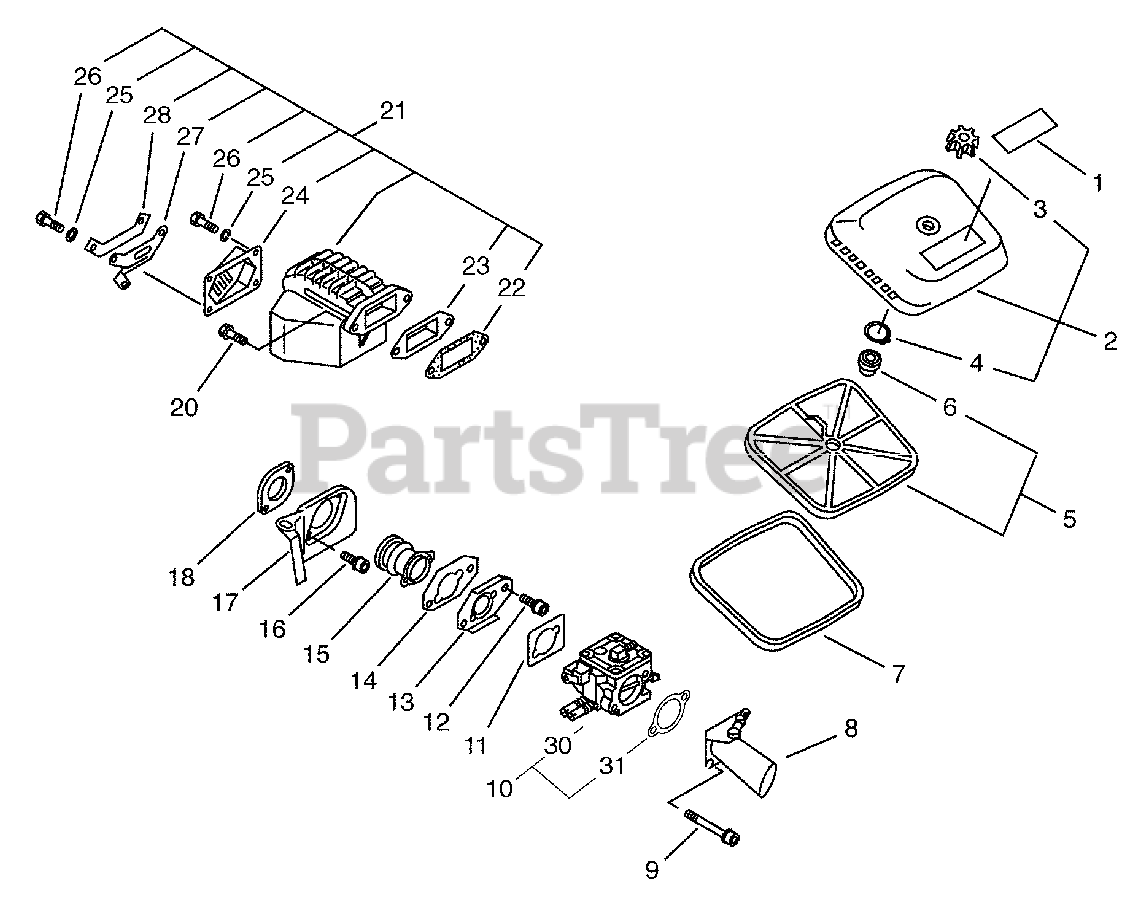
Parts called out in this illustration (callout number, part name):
1	LABEL - MODEL
2	AIR FILTER COVER ASSY
3	THUMBSCREW
4	RING, RETAINING - 11
5	FILTER, AIR
8	ADAPTOR, INTAKE
9	SCREW - 5X50
10	CARBURETOR KIT
12	SCREW - 5X14
13	ADAPTOR, CARBURETOR
14	SEAL, DUST
15	BELLOWS, INTAKE
16	SCREW - 5X20
18	RETAINER
20	SCREW - 6X25
21	MUFFLER ASSY
22	GASKET, EXHAUST
23	DIFFUSER, EXHAUST
24	PLATE, EXHAUST
25	WASHER - 5
26	SCREW - 5X15
28	WASHER
30	CARBURETOR
31	GASKET, INTAKE
